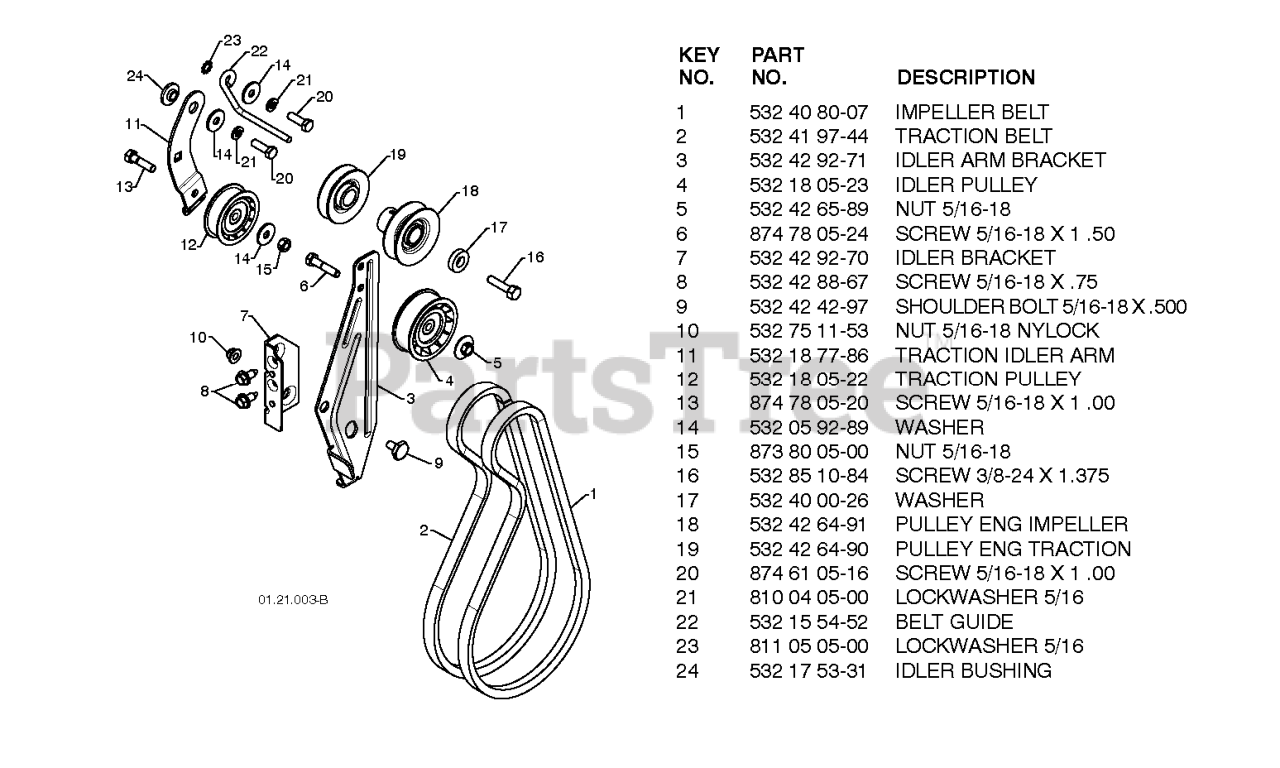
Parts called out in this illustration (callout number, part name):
1	BELT.V.IMPELLER
2	V-BELT TRACTION 34.25
3	ARM.IDLER.BRAKE.
4	PULLEY.W/SPACER.2.75
5	NUT.FLANGE.HEX.5/16X18.BLACK
6	HEX BOLT
7	RP BRACKET.IDLER.PIVOT
8	BOLT.HEX.HD.WASHER.5/16-18X.75
9	BOLT.SHOULDER.1/2X12
10	NUT.LOCK.5/16-18
11	ARM, IDLER
12	PULLEY.W/SPACER.2.25
13	BOLT.5/16-18X1-1/4 FULL.THREAD
14	STEEL WASHER
15	NUT.71038.31-18.HEX.NYLOCK
16	SCREW, HEX HD 3/8-24 X 1-3/8
17	WASHER, FLAT 3/8
18	PULLEY.IMPELER.
19	PULLEY.ENG.TRACTION
21	WASHER.LOCK.HVY.HLCL.SPR.5/16
22	BELT.GUIDE.RH
23	WASHER EXT TOOTH LOCK 5/16
24	RP BUSHING, IDLER PIVOT
